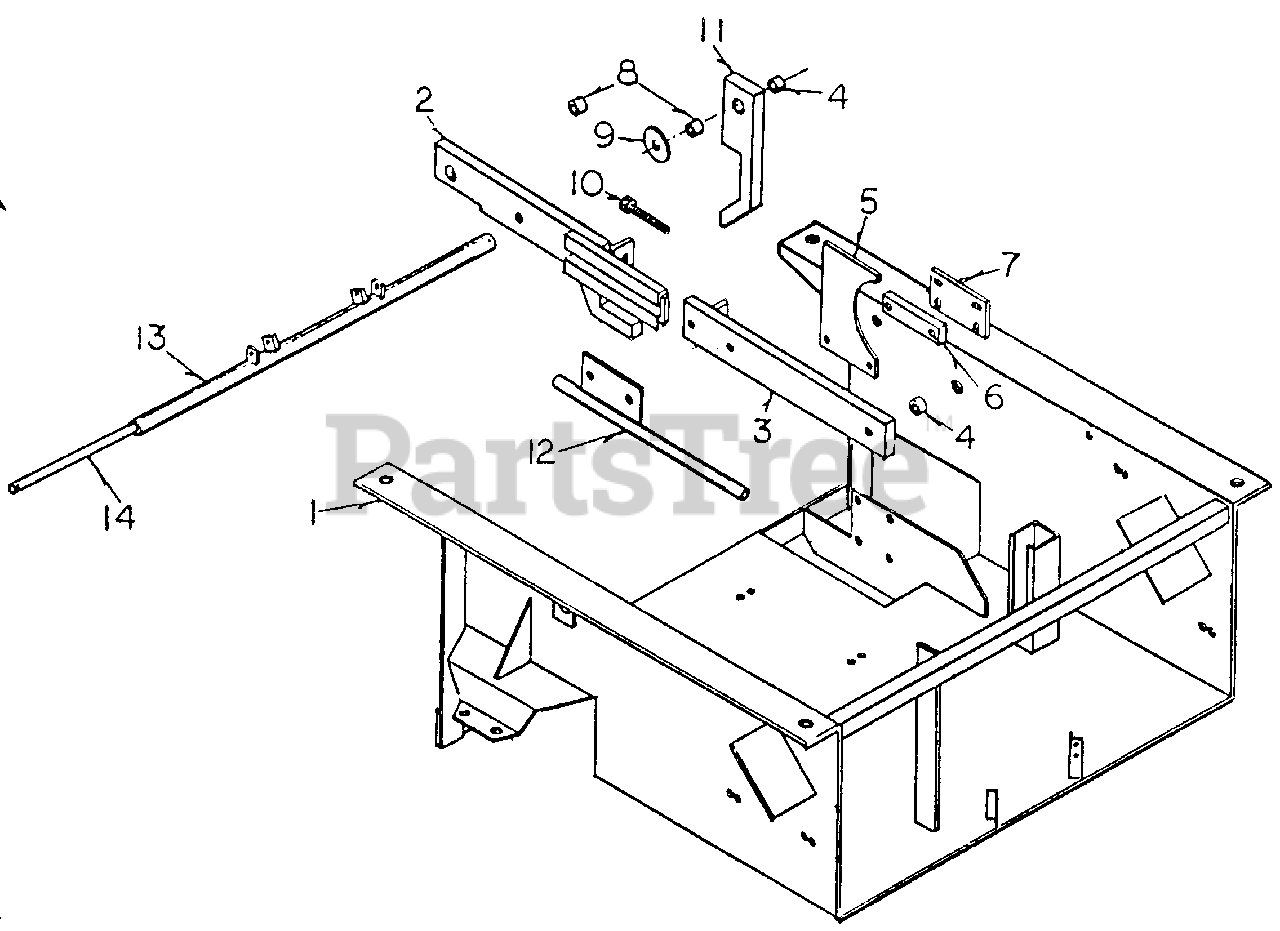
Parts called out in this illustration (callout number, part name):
1	Base
2	RH Deck Llft Arm, Front RH
3	Deck Lift Arm, Back
4	Bushlng, Short
5	Belt Retalner
6	Belt Retalner Spacer
7	Belt Retalner Mount
8	Bushing, Long
10	Deck Belt Adjustment Bolt
11	Forward Nose Down Lock
14	Cross Bar Pin
